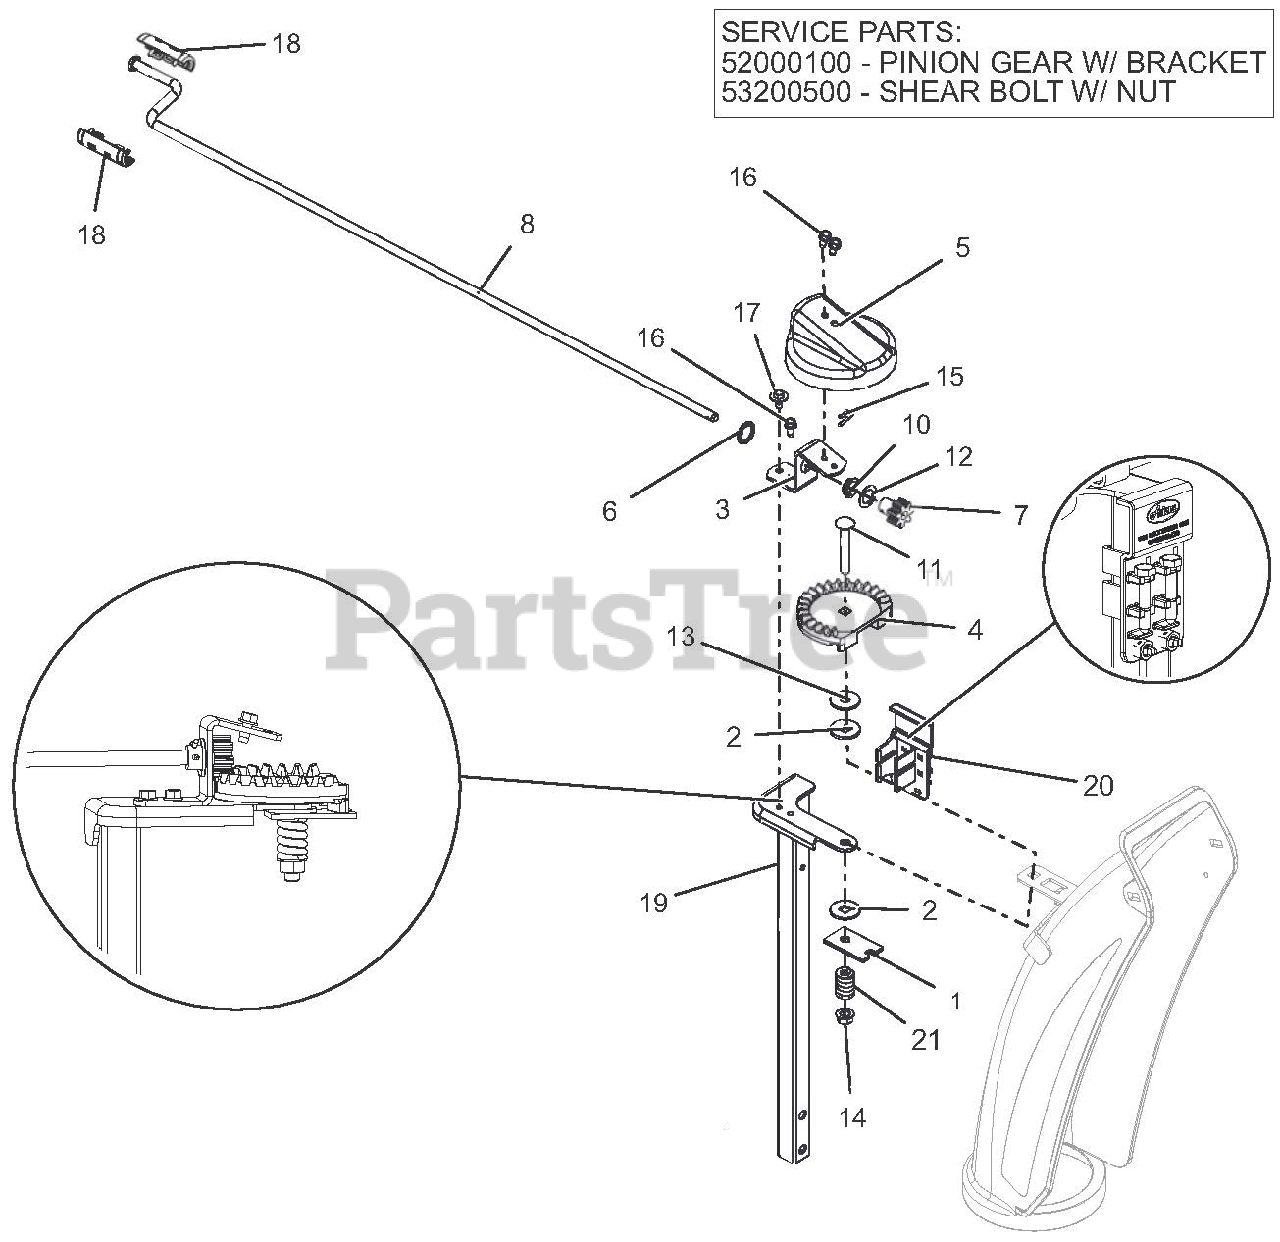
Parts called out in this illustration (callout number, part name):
1	PLATE, FRICTION
2	FRICTION WASHER
3	BRACKET, PINION GEAR
4	CHUTE GEAR
5	GEAR COVER
6	PUSHNUT .625
7	PINION GEAR - CHUTE
8	ROD, CHUTE CRANK, COMP&SNOTEK
10	BUSHING, POLYLINER-.63 SNAPIN
11	@BLT-RDHDSQNK .38-16X2.50 G5YZ
12	WSHR-THRST .625 X 1.0 X .03
13	@WSHR-FL-STL .406X1.25X.10 ZC
14	@NUT-LK-TOP-FLG .38-16 YWZC
15	PIN, SPRING CLIP
16	SCR-TAP .25-20X.50 HWH TR YWZ
17	SCR-TAP .25-20X.50 LGHWH TR YZ
18	KNOB, CHUTE CRANK - SNAP BLK
19	CHUTE PEDESTAL, TALL COMPACT
20	HOLDER W SMALL SHEAR BOLT /NUT
21	SG-COMP .187X.56X1.62
22	PINION GEAR W/BRACKET
23	SHEAR BOLT WITH NUT
